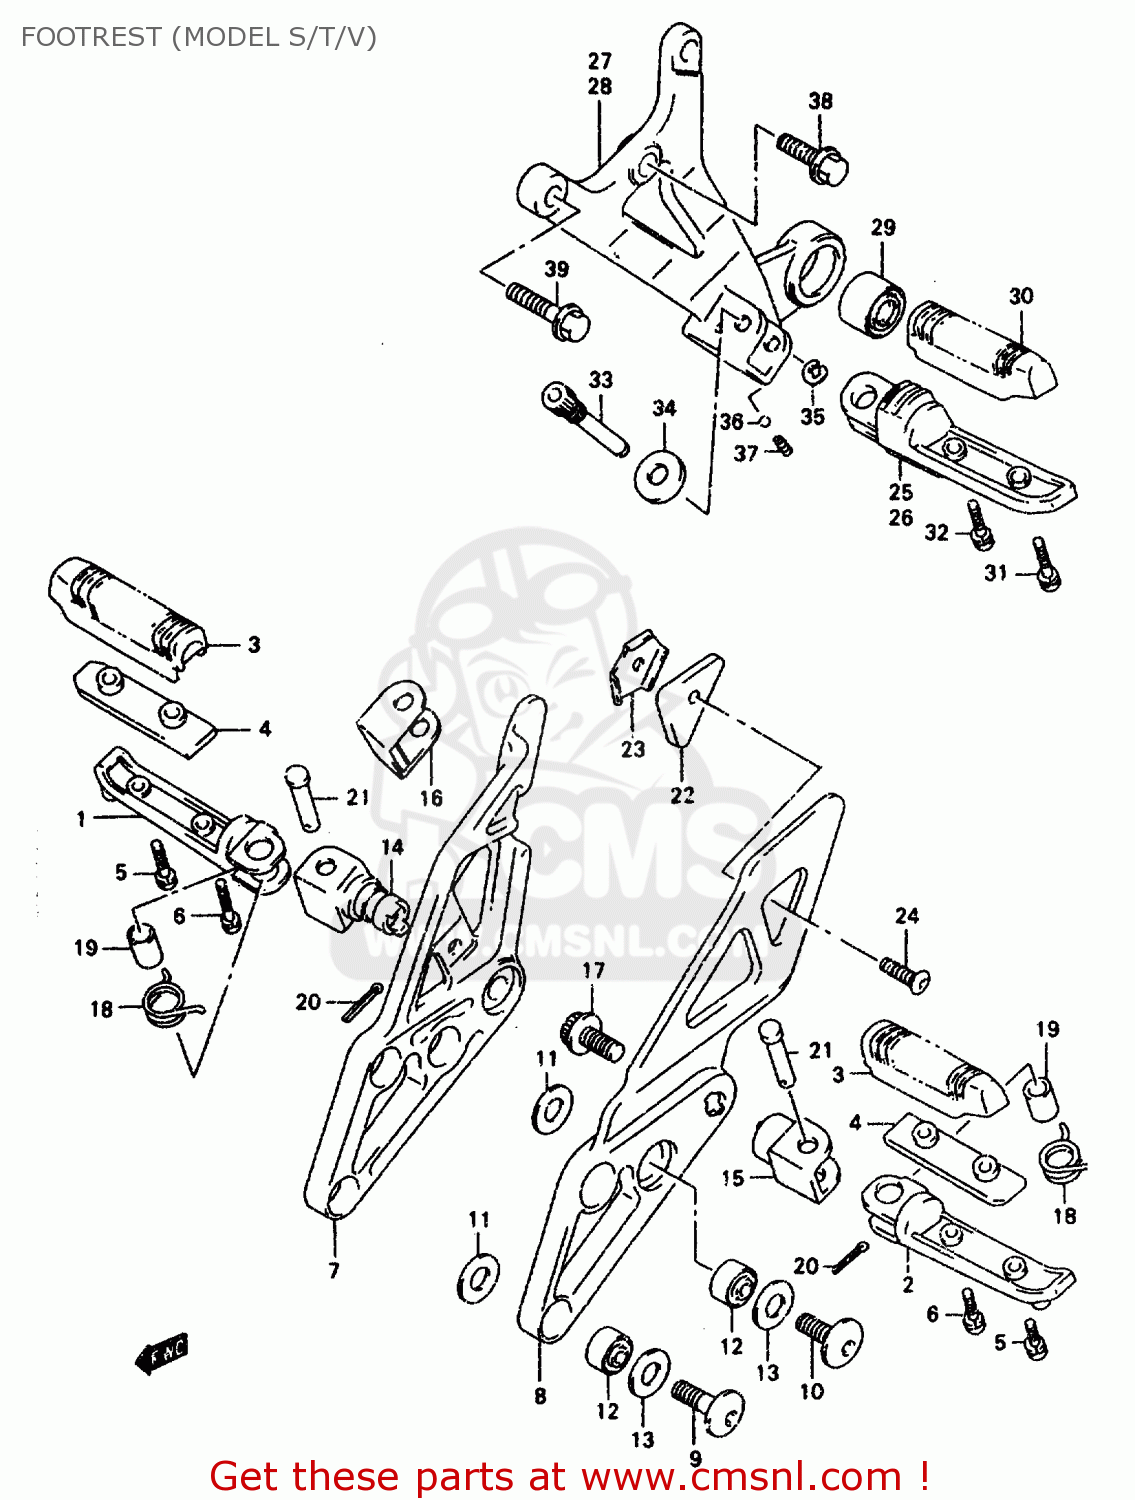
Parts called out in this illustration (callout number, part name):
1	BAR,FOOTREST,R
2	BAR,FOOTREST,L
3	RUBBER,FOOTREST
4	BAR,FR FOOTREST NO.2
5	SCREW
6	SCREW
7	BRACKET,FOOTREST,R
8	BRACKET,FOOTREST,L
9	BOLT L:30
10	BOLT(8X25)
11	WASHER (8.2X24X1.6)
12	BUSH(12X20X16)
13	WASHER(12.6X24X1.9)
14	HOLDER,FOOTREST
15	HOLDER,FOOTREST,L
16	CUSHION,FR FOOTREST
17	BOLT(10X24)
18	SPRING
19	SPACER(8.1X12X22)
20	PIN 20X15
21	PIN
22	WEIGHT,FOOTREST BRACKET,L
23	COVER,FOOTREST WEIGHT
24	SCREW(6X20)
25	BAR,PILLION FOOTREST,R
26	BAR,PILLION FOOTREST,L
27	BRACKET,PILLION FOOTREST,R
28	BRACKET,PILLION FOOTREST,L
29	BUSHING 10X28.1X19
30	RUBBER,FOOTREST
31	SCREW
32	SCREW
33	BOLT,PILLION FOOTREST
34	WASHER
35	E.RING
36	BALL
37	SPRING
38	BOLT
39	BOLT
